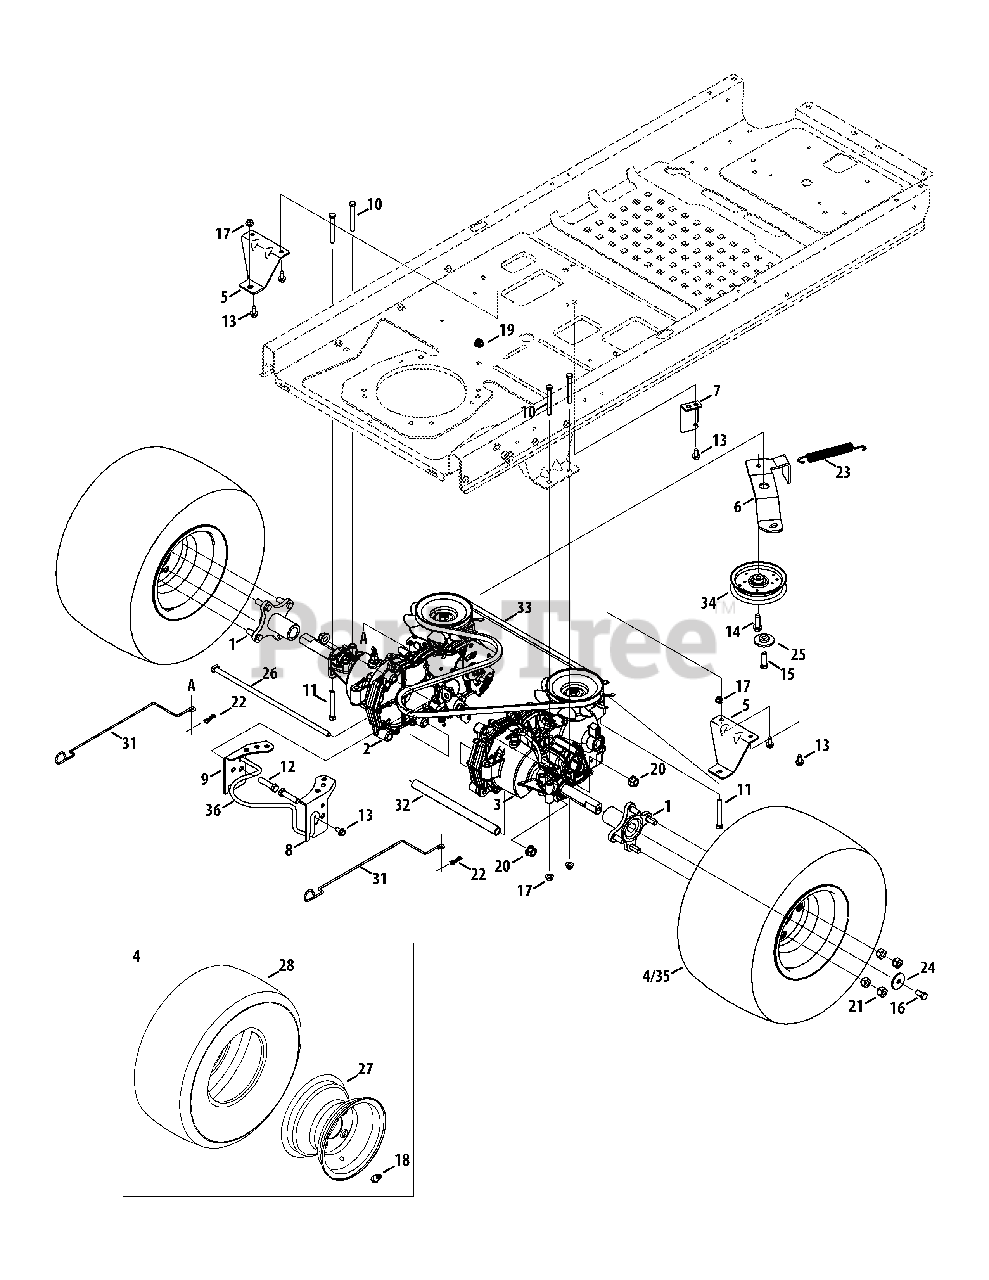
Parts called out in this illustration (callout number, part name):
1	Wheel Hub Assembly
2	Transmission Assembly, LH
3	Transmission Assembly, RH
4	Complete Wheel, 18 x 8.5-8
5	Transmission Mounting Bracket
6	Idler Bracket
7	Spring Mounting Bracket
8	Transmission Bracket
9	Transmission Bracket
10	Hex Screw 5/16-18 x 2.75
11	Hex Screw 5/16-18 x 2.25
12	Hex Screw 7/16-20 x 1.75
13	Hex Washer Screw 5/16-18 x .750
14	Hex Washer Screw 3/8-16 x 1.250
15	Hex Screw 3/8-16 x 1.00
16	Hex Screw 3/8-16 x .75
17	Flange Lock Nut 5/16-18
18	Valve Tubeless
19	Flange Lock Nut 3/8-16
20	Flange Lock Nut 7/16-20
21	Lug Nut 7/16-14
22	Bow-Tie Cotter Pin
23	Extension Spring .75 Dia. x 6.02
24	Flat Washer .390 x 1.50 x .134
25	Shoulder Spacer .884 x .190
26	Rod .328 Dia. x 14.0 Lg.
27	Rim Only,
28	Tire Only 18 x 8.5-8 CARLISLE
28	Tire Only 18 x 8.5-8 DELI
31	Bypass Rod
32	Tube .51 ID x .75 OD x 10.2
33	Belt A-Type x 67.0
34	Idler Pulley 4.25 Dia.
36	Engine Keeper Rod
